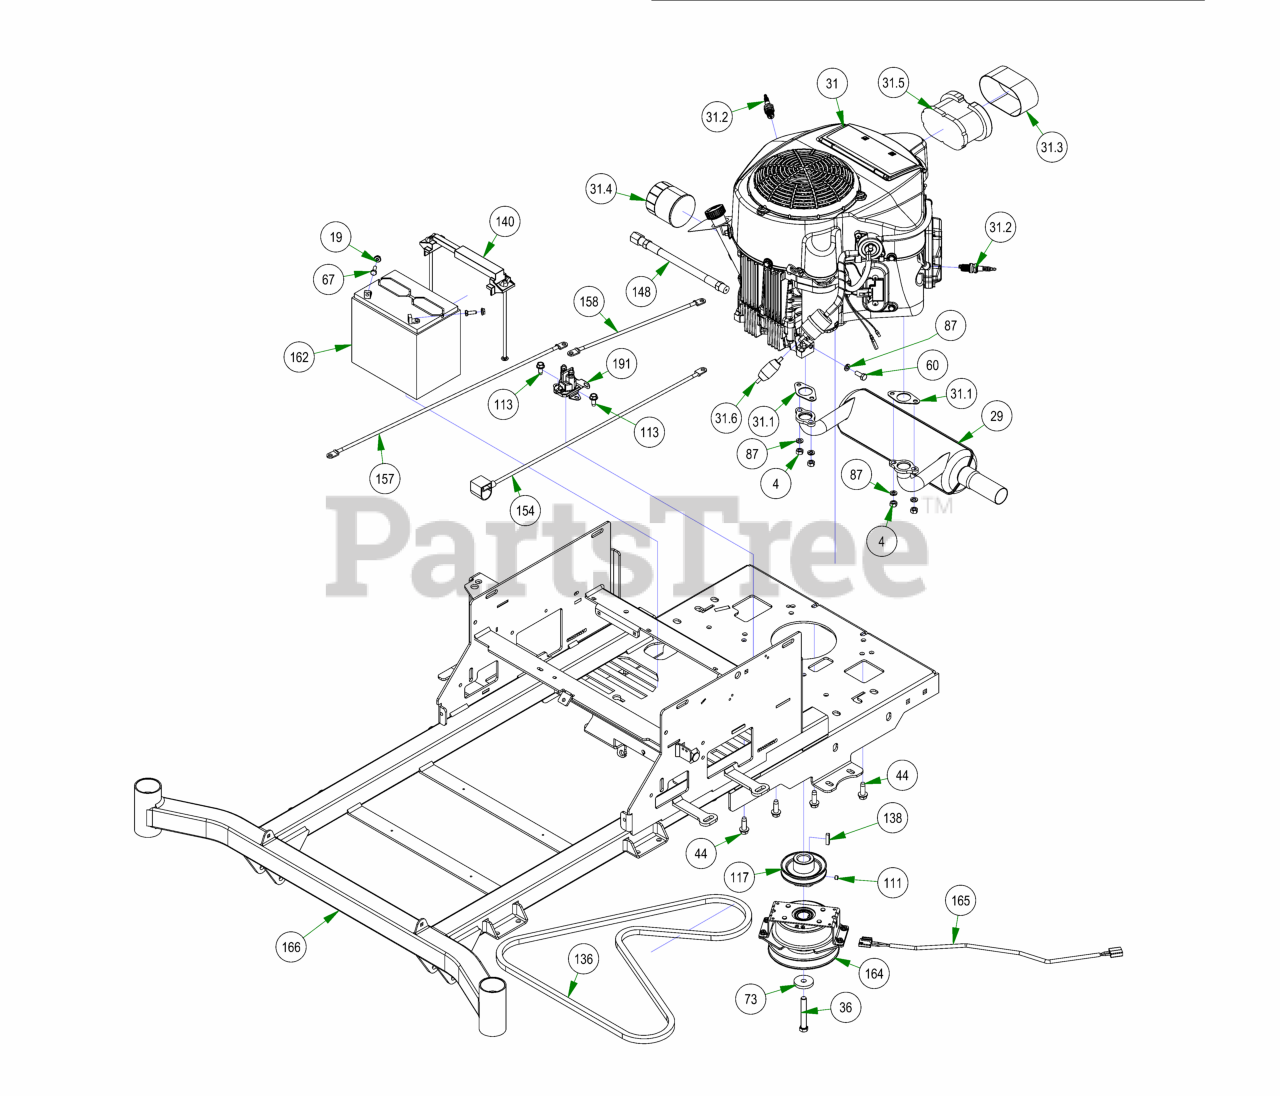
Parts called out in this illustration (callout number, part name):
4	M8-1.25 DIN 934 HEX NUT (CL.8) ZINC
19	1/4-20 HEX SERRATED FLANGE NUT HARD/ZINC
29	Kawasaki Muffler 1251
31	Kawasaki FR691 29.5HP
31.1	Exhaust Gasket
31.2	Spark Plug - Kawasaki
31.3	Air Filter Pre-Cleaner for KAW
31.4	22-26 Kaw Oil Filter FR Engine
31.5	Kawasaki Air Filter
31.6	Universal Inline Fuel Filter
36	7/16-20x3” Hex Bolt GR 8 W/ Patch
44	3/8-16 X 1-1/8 HEX WASHER UNSLOT SERRATED (TRI-LOB) TRS ZINC YELLOW
60	M8-1.25 X 20MM DIN 933 HEX TAP BOLT (CL 8.8) ZINC
67	1/4-20 X 3/4 HEX CAP SCREW (GR.5) ZINC
73	CLUTCH WASHER
87	5/16 SPLIT LOCKWASHER ZINC
111	5/16-24 X 1/4 SOCKET SET SCREW (CUP PT) PLAIN
113	5/16-18 X 3/4 HEX WASHER SLOT (F) TCS ZINC
117	3-3/4" Motor Pulley
138	1/4 X 1 SQ MACHINERY KEY 1018 STL PLN
140	Hold Down Assembly
148	Oil drain Hose
154	24 inch Black Cable – MZ/ZT
157	24" Red Battery Cable
158	12 in red battery cable
162	SP-35 Battery
165	Clutch Pigtail
166	2022 MZ/ZT 54"-60" Frame
